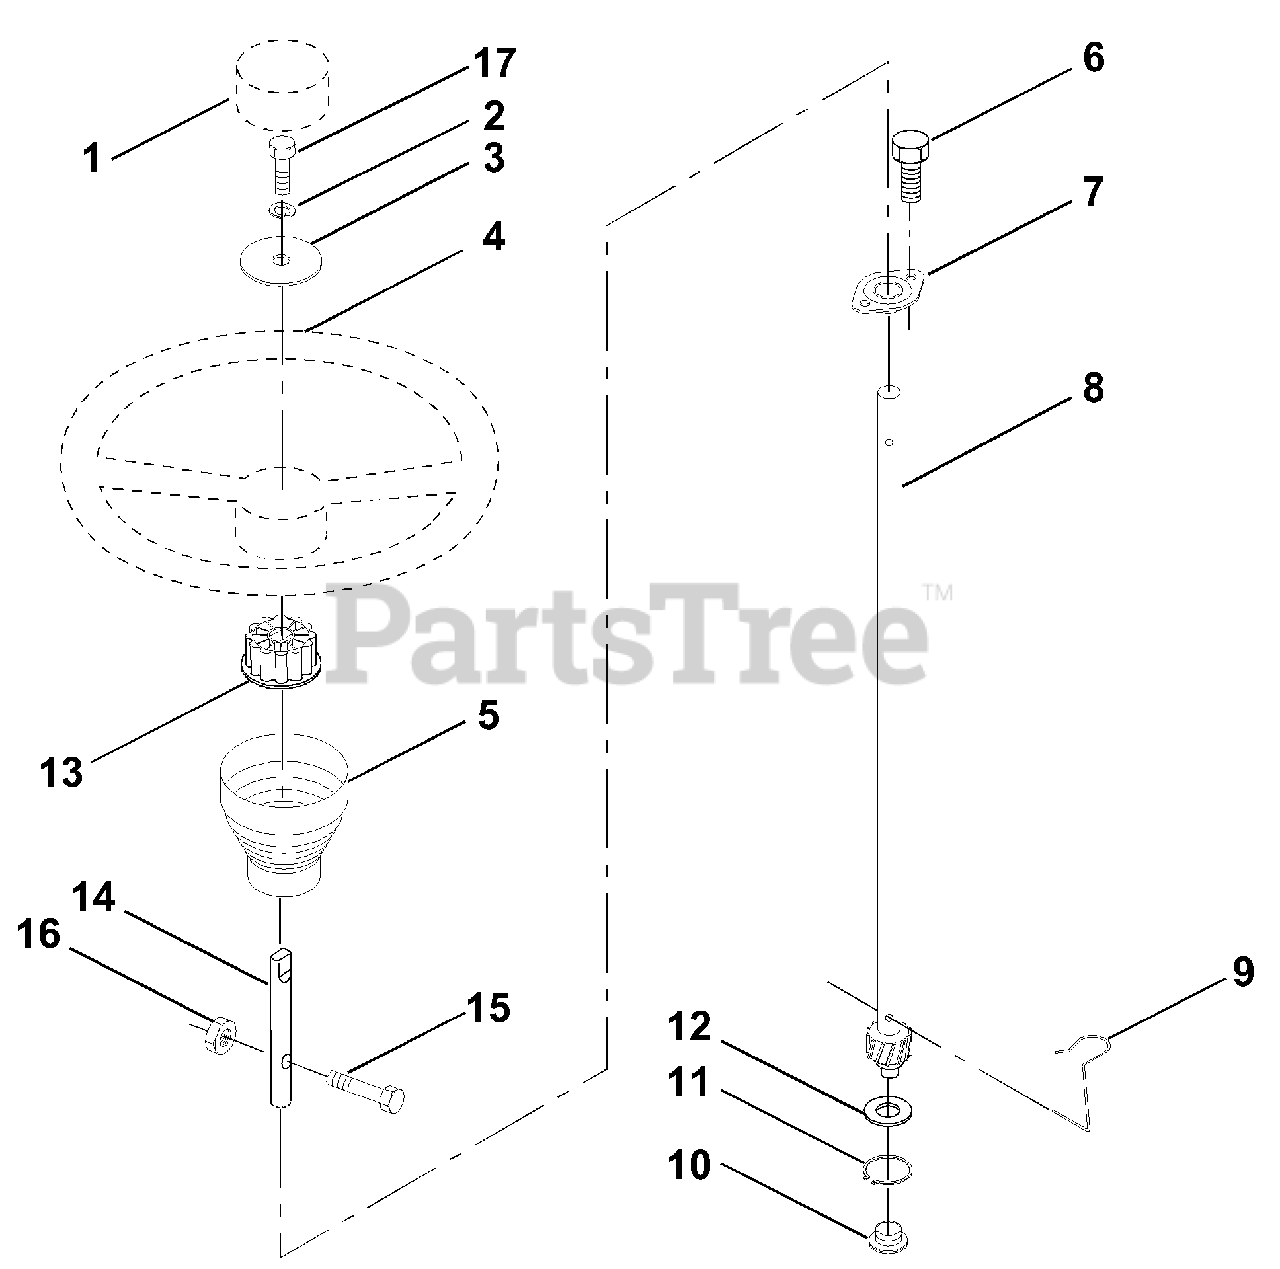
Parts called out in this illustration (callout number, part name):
1	Insert, Wheel, Steering
2	Washer, Lock Hvy. Hlcl
3	Washer 12/32 x 2-3/8 x 8 Ga.
4	Wheel, Steering
5	Sleeve, Steering
6	Screw, Hex #10-16 x 1/2 TY-B
7	Bushing, Steering
8	Shaft, Steering
9	Clip, Steering
10	Bushing, Lower, Steering
11	Ring, Retaining
12	Washer 21/32 x 1 x 16 Ga.
13	Adaptor, Wheel, Steering
14	Extension Shaft
15	Bolt, Fin, Hex 5/16-18 UNC x 1-1/4
16	Nut Lock, Hex W/Ins 5/16-18 UNC
17	Bolt, Fin Hex 3/8-16 UNC x 1
